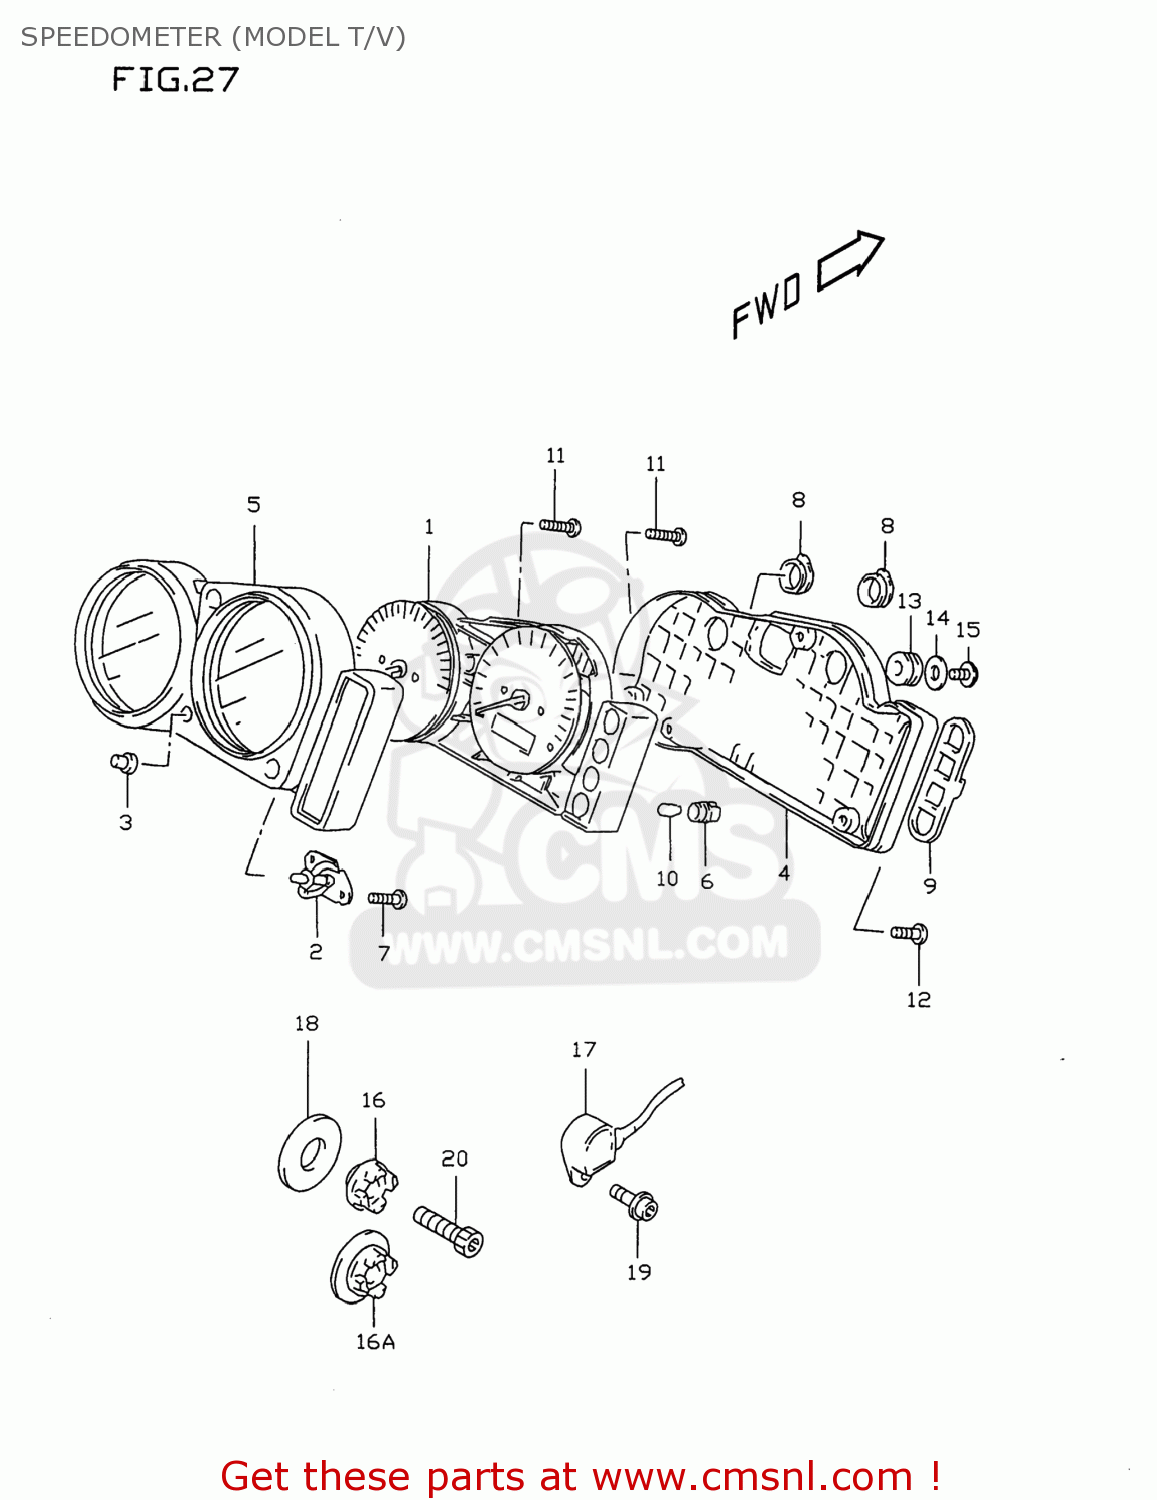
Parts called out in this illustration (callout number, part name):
1	METER ASSY,SP&
2	ATTACHMENT,SWITCH
3	SWITCH,GUM
4	CASE ASSEMBLY
5	VISOR
6	SOCKET(T:6.5)
7	SCREW,PAN HEAD
8	CAP,BLIND NO.1
9	CAP,BLIND NO.2
10	BULB(12V1.7W,T6.5)
11	SCREW
12	SCREW
13	CUSHION,METER
14	WASHER(5.5X16X1.2)
15	SCREW
16	ROTOR,SPEED
16A	ROTOR,SPEED
17	SENSOR,SPEED
18	WASHER(14.2X34X1)
19	BOLT
20	BOLT
